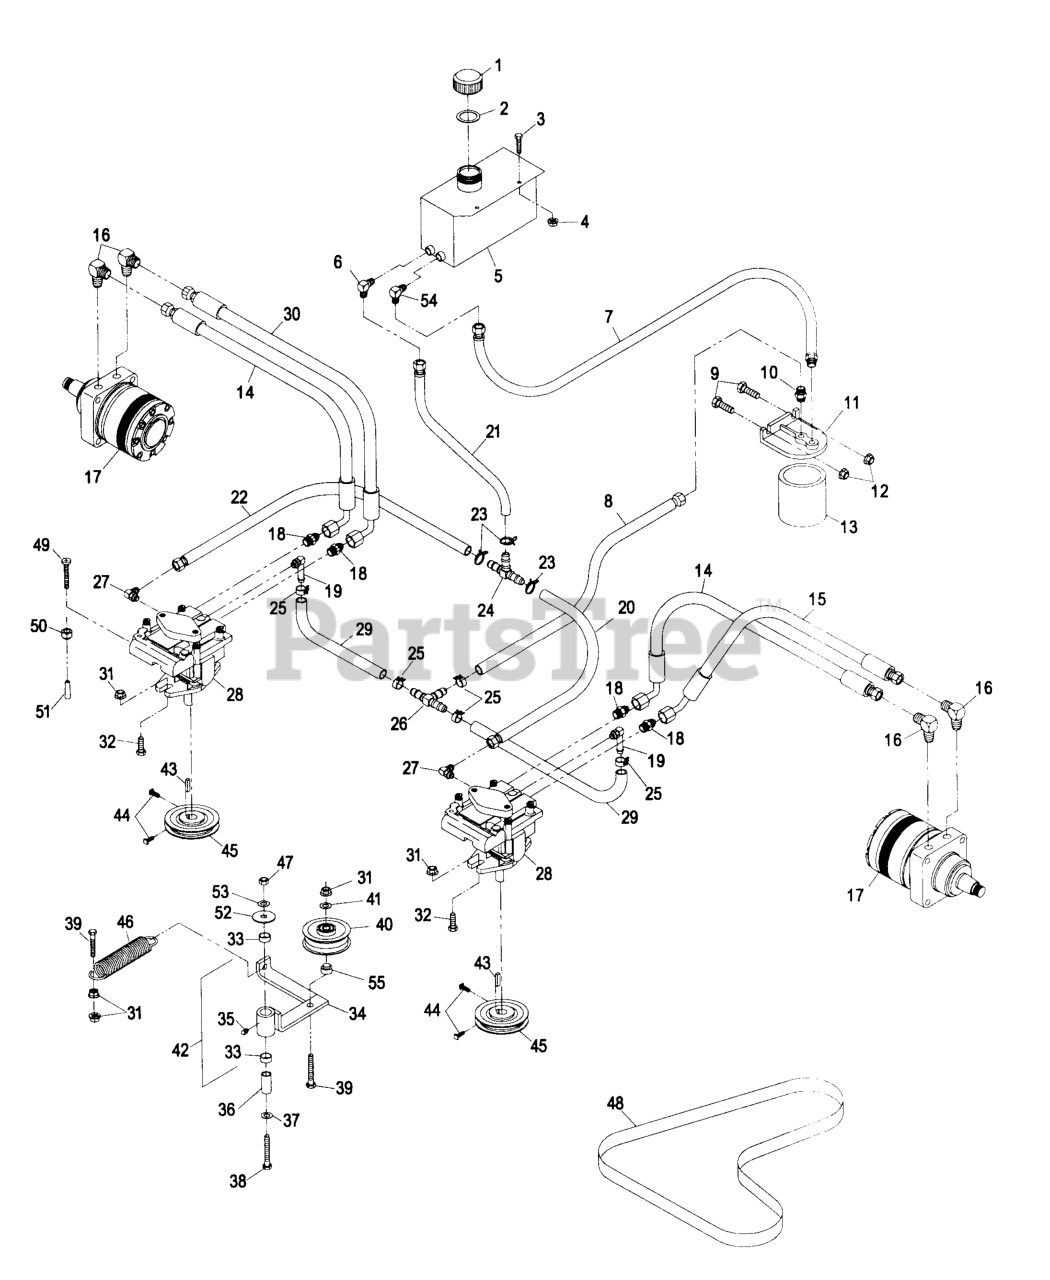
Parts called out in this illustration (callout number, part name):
2	GASKET-CAP, TANK
6	FITTING-ELBOW
10	FITTING-STRAIGHT
14	HOSE-FRONT
15	HOSE, LH REAR
16	FITTING-HYD, 90 DEG
17	MOTOR-WHEEL
18	FITTING-STRAIGHT
19	FITTING
20	HOSE ASM
22	HOSE ASM
23	CLAMP-HOSE
24	FITTING-TEE, HOSE
25	CLAMP-HOSE
26	FITTING-TEE, HOSE
27	FITTING-90 DEG
30	HOSE-REAR, RH
33	SLEEVE-BEARING
36	BUSHING
44	SCREW-SET
46	SPRING-EXTENSION
51	GRIP-VALVE, DUMP
54	FITTING-ELBOW
55	BUSHING-IDLER
